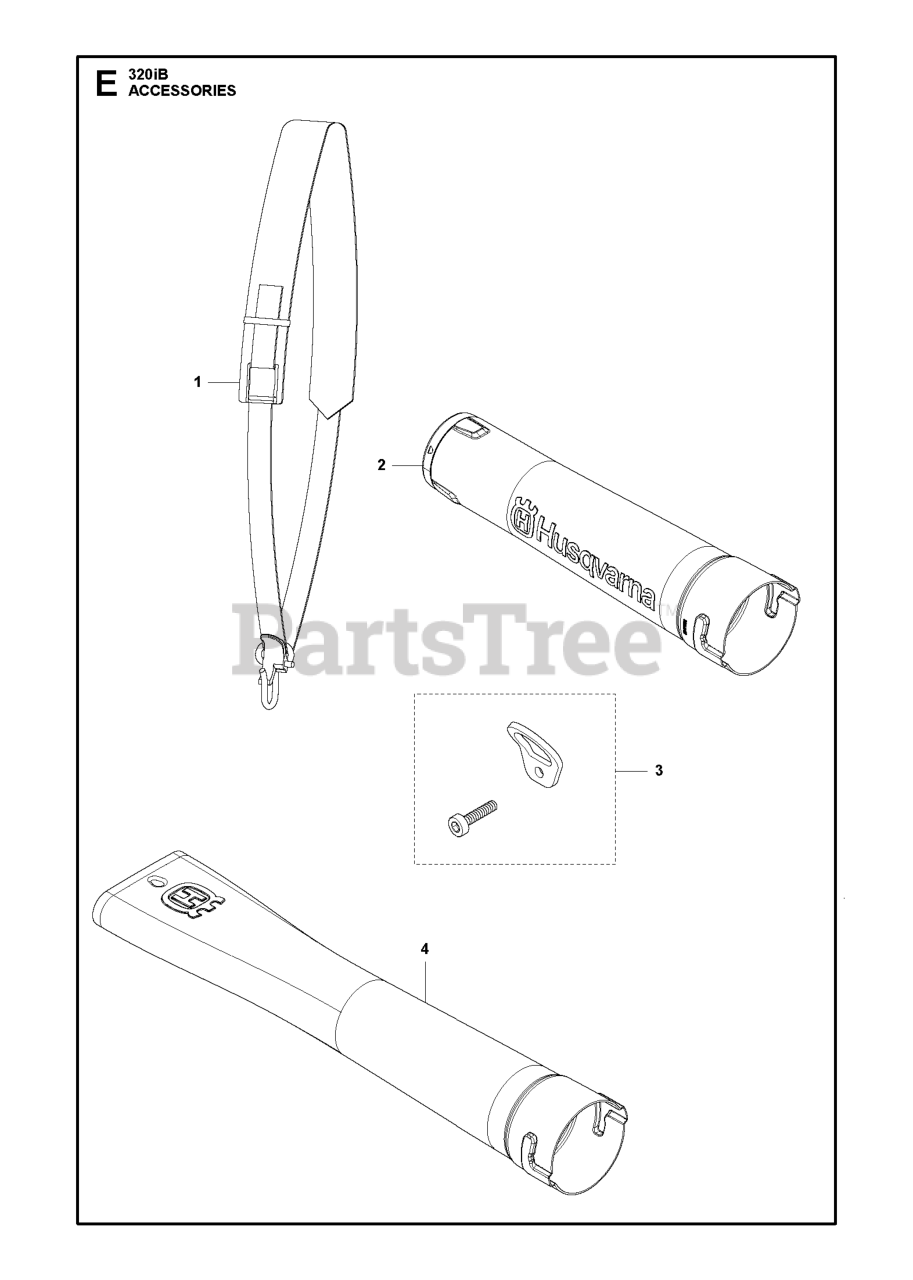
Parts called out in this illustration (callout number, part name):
1	Harness-w/o warning
2	TUBE ASSY NOZZLE 536LIBX
3	KIT EYELET
4	BLOWER NOZZLE FOR 320IB
